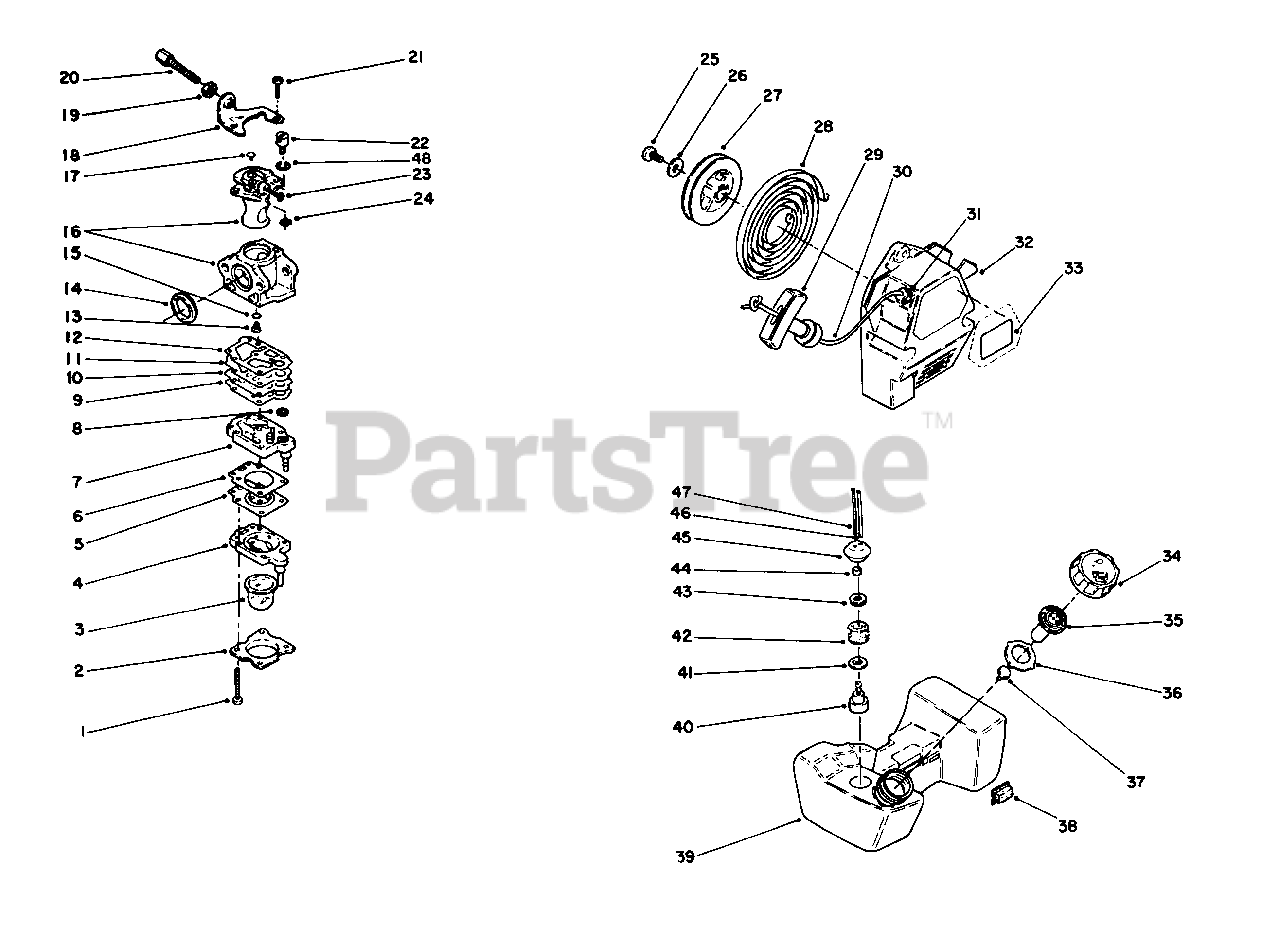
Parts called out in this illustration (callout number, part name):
2	Cover-Primer
3	Bulb-Primer
4	Body-Primer
5	Diaphragm
6	Gasket-Diaphragm
7	Body Assembly (Incl. Ref. #8)
9	Gasket-Pump
11	Diaphragm
12	Gasket-Diaphragm
13	Jet-Main #43
15	"O" Ring-Main Jet
16	Body-Carburetor (Ref.)
19	Nut-Lock
20	Screw-Adjustment
22	Swivel-Cable
23	Valve-Throttle
28	Spring-Recoil
29	Handle-Recoil
30	Rope-Recoil
31	Guide-Rope
32	Case-Recoil
33	Decal-Toro
34	Cap-Fuel
35	Valve-Breather
37	Cap-Valve
39	Tank Assembly-Fuel (Incl. Ref. #34-37 & 40-47)
40	Weight-Filter
41	Washer-Seal
42	Filter-Fuel
43	Washer-Seal
45	Grommet-Fuel Tank
46	Hose-Fuel
47	Tube-Fuel Return
